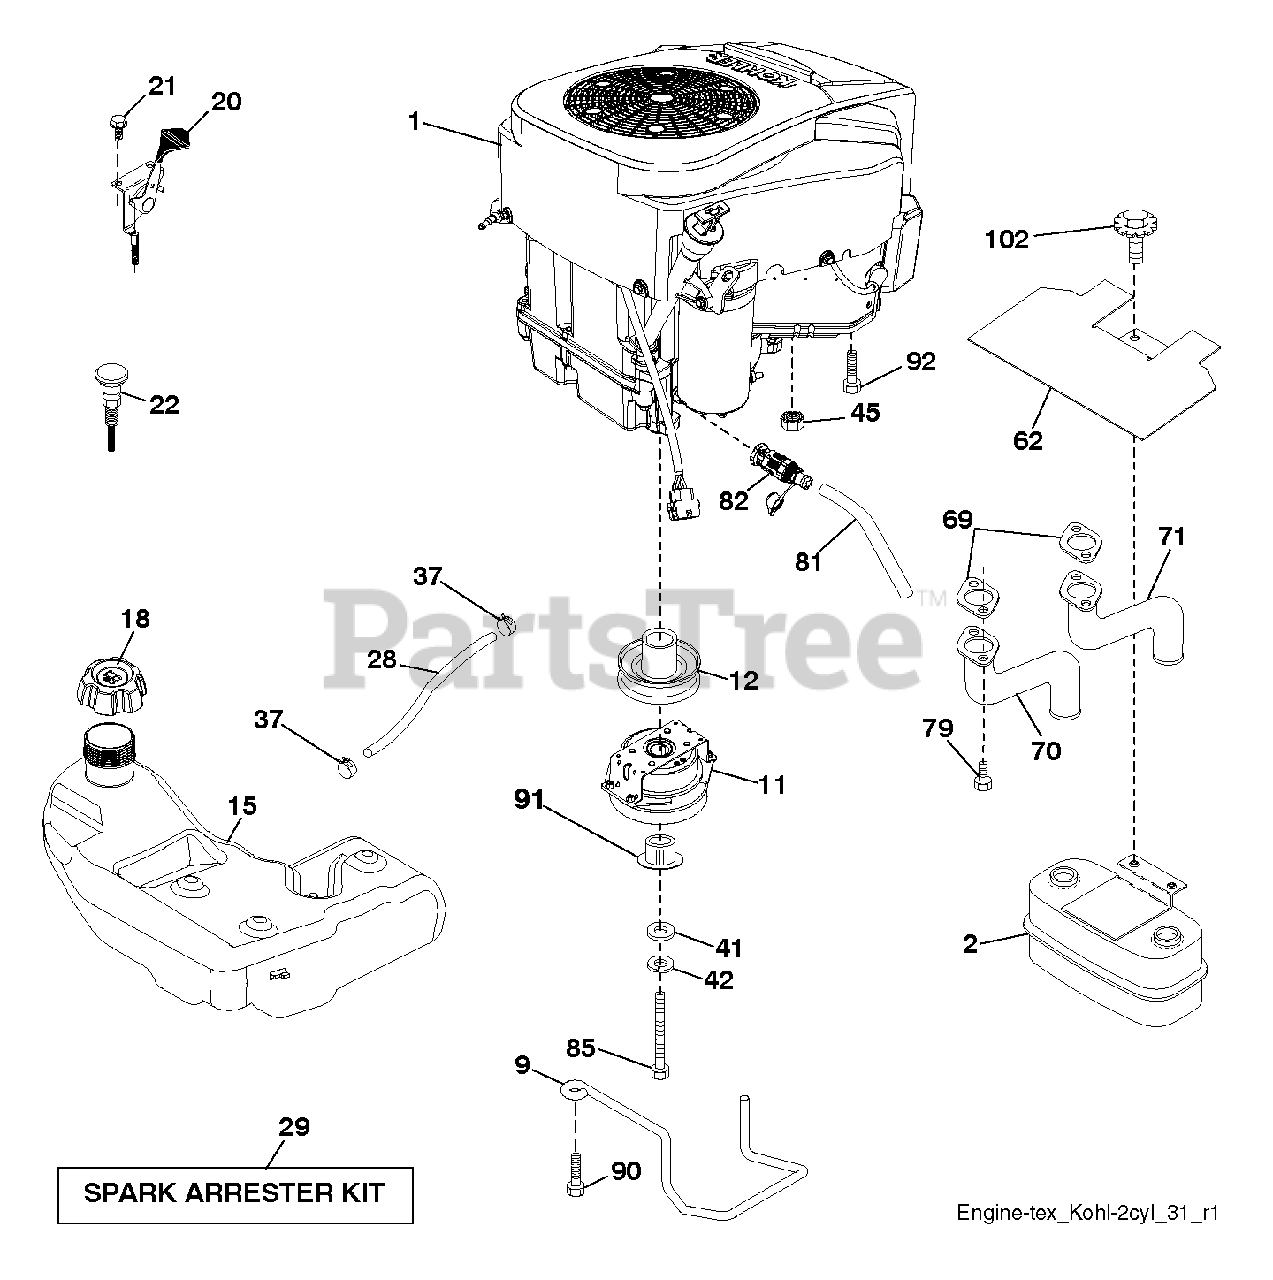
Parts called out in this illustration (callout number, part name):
2	MUFFLER.ASM.TWN.EXTNDED.DFLCTR
9	KEEPER.BELT.ENGINE
11	Clutch, Ogura 5.0Pd Gt1.5A-Eh07
12	PULLEY.ENGINE.ENX
15	TANK.ASSY.3.GAL.EPA
18	Fuel Cap Assembly, 3" Black
20	THROTTLE CONTROL
21	SCREW.#10 X 0.750.BOS (2 2)
22	CONTROL CHOKE
28	LINE.FUEL.64"REAR.EMIS
29	KIT.SPARK ARRESTOR(392390 B&S)
37	HOSE CLAMP
42	LOCKWASHER
45	NUT
62	SHIELD.HEAT.MUFFLER
69	GASKET.EXHAUST.KOHL.CV18-CV26
70	Exhaust Pipe, LH CV18/20
71	Exhaust Pipe, RH CV18/20
79	SCREW.SOCKET HD.5/16-1
81	TUBE, DRAIN OIL ASM.
82	VALUE.OIL.DRAIN
85	Hex Bolt, 7/16-20 X 3.75 Gr5 Red
90	SCREW 3/8-16X1
91	BUSHING.1.375OD
92	SCREW 3/8-16X1
102	SCREW
